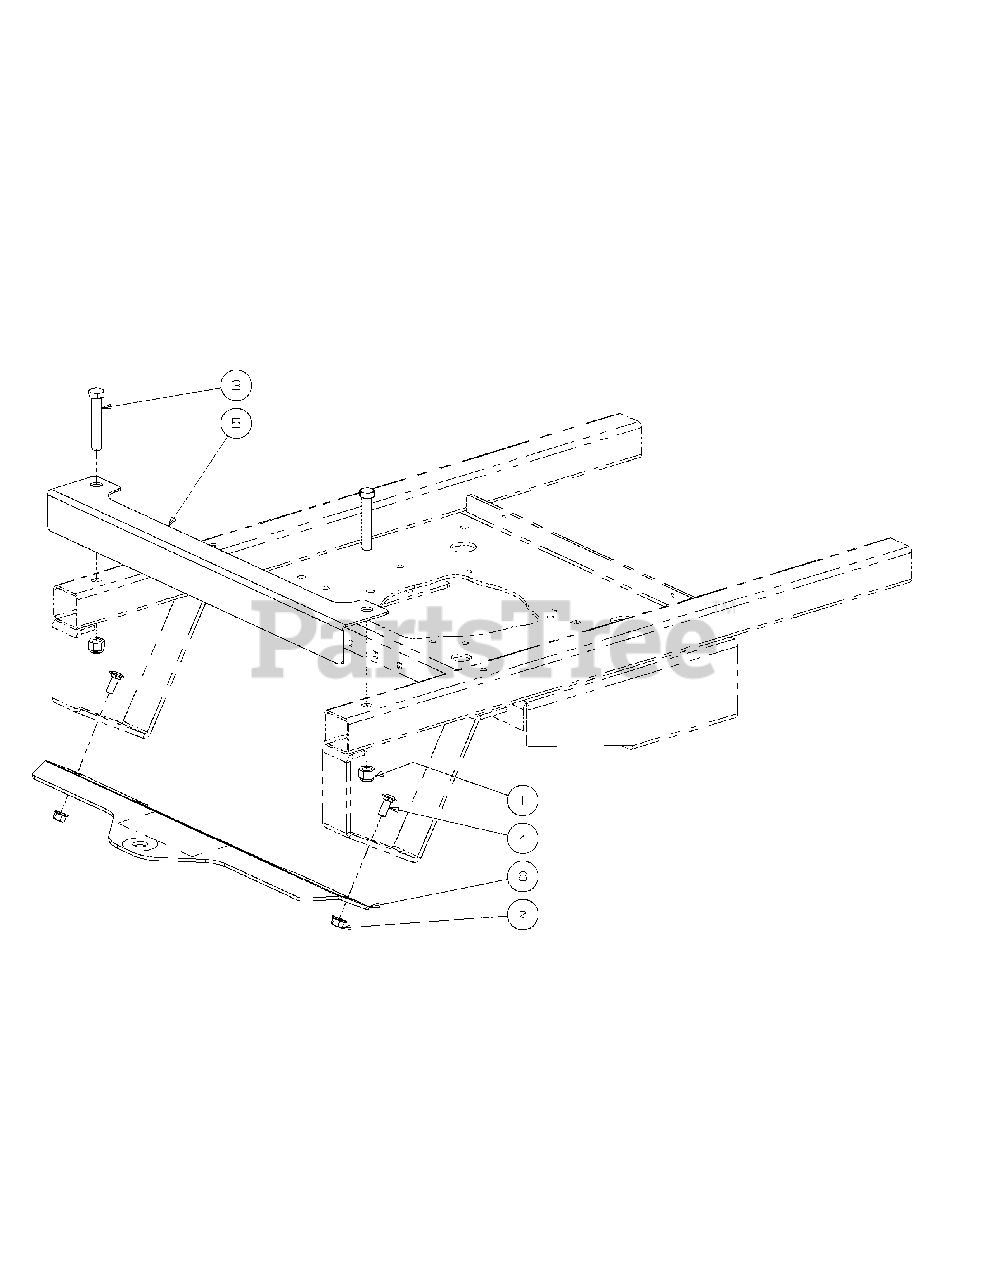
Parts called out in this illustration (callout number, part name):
1	Hex Nut, 1/2-13, Insert Lock
2	Flange Lock Hex Nut, 3/8-16
3	HHCS, 1/2-13, 3.00
4	Carriage Bolt, 3/8-16 x 1.00
5	Bumper Assembly
6	Hitch Bracket
